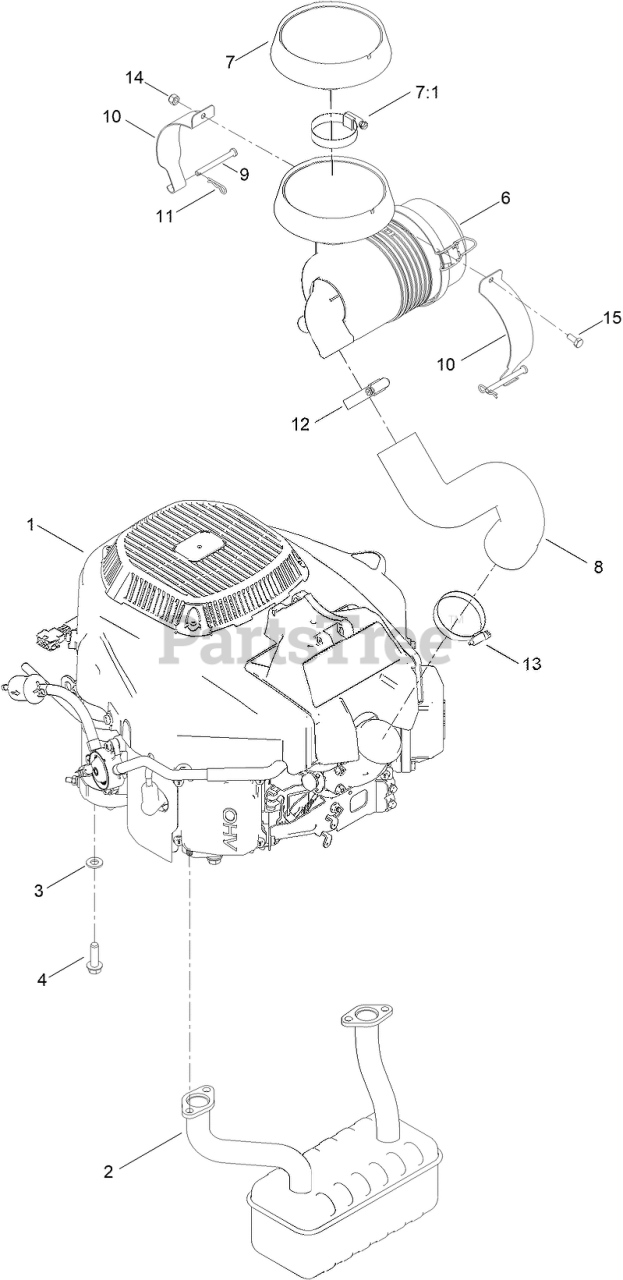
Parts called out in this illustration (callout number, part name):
1	ENGINE-2P77F-HD
2	MUFFLER
3	WASHER-FLAT
4	SCREW-THD
6	AIR CLEANER ASM
7	RAIN CAP KIT
7:1	CLAMP-HOSE
8	HOSE-INTAKE
9	PIN-CLEVIS
10	STRAP-CANISTER, AIR
11	PIN-COTTER
12	CLAMP-HOSE
13	CLAMP-HOSE
14	NUT-HEX
15	SCREW-HH
